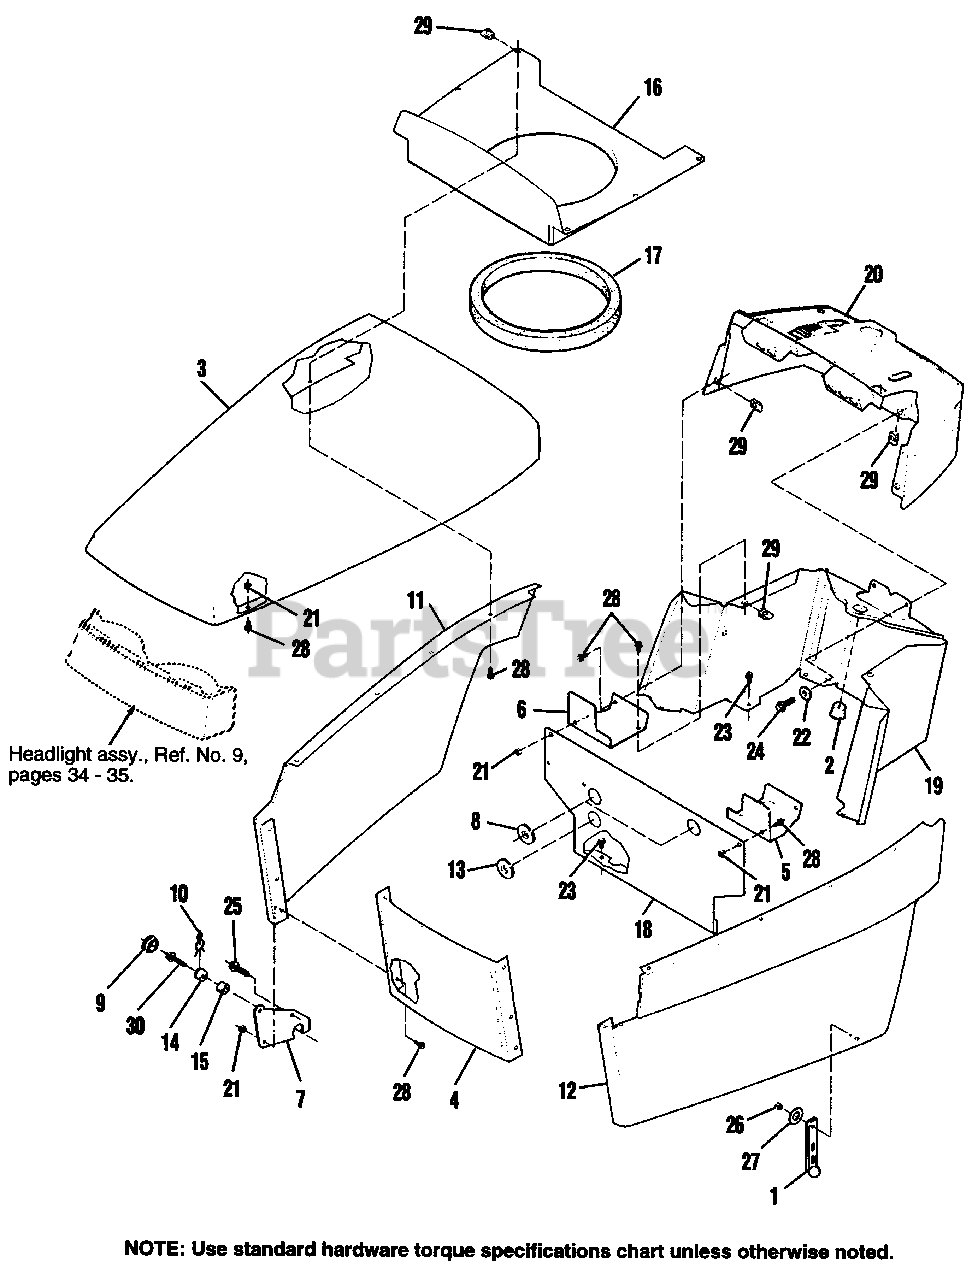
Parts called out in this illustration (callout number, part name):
1	STRAP, Hood
2	BUSHING, Nylon
3	HOOD (Orange)
3	HOOD (Red)
4	GRILLE
5	SUPPORT, Bulkhead, LH
6	SUPPORT, Bulkhead, RH
7	HINGE, Hood
8	GROMMET, Bulkhead
9	SPACER, Hood
10	CLIP, Hairpin
11	SIDE PANEL ASSY., RH (Orange)
11	SIDE PANEL ASSY., RH (Red)
12	SIDE PANEL ASSY., LH (Orange)
12	SIDE PANEL ASSY., LH (Red)
13	GROMMET, Wire Harness
14	PIVOT, Hood
17	SEAL, Air Duct
18	BULKHEAD
19	DASH, Lower
21	NUT, Hex, Full Lock, 1/4-20
22	WASHER, Plain, 1/4
23	SCREW, Taptite, 1/4-20 x 1/2
24	CAPSCREW, Whizlock, 1/4-20 x 3/4
25	SCREW, Taptite, 5/16-18 x 5/8
26	NUT, Hex, Lock, Nylon #10-24
27	WASHER, Special
28	CAPSCREW, Whizlock, 1/4-20 x 5/8
29	PAL NUT, 1/4-20
30	SCREW, Taptite, 5/16-18 x 1
